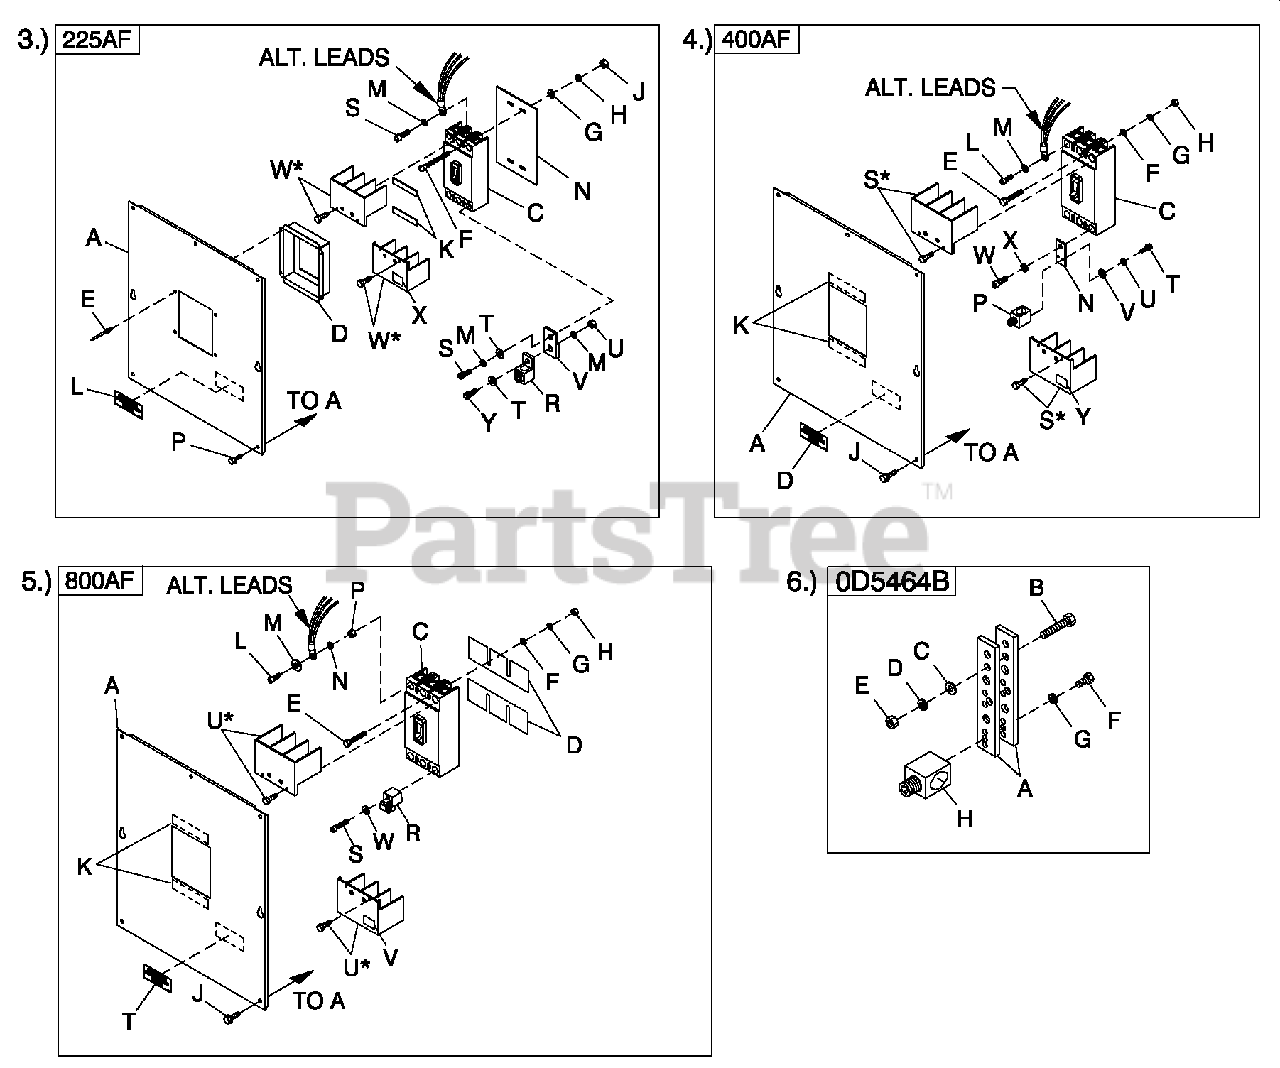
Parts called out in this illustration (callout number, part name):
A	COVER C B C 5 225AF
C	CIRCUIT BREAKERS 200A FRAME
D	COVER CB DISH 225AF
E	RIVET POP .125 X .275 S S
F	SCREW RHM #8-32X3-1/4
G	W ASHER FLAT #8 ZINC
H	WASHER LOCK #8-M4
J	NUT HEX #8-32 STEEL
K	TAPE ELEC 1/2 FOAM
L	DECAL CUSTOMER CONNECT INSIDE
M	W ASHER LOCK M8-5/16
N	INSULATOR CB225AF
P	SCREW THF M6-1 X 16 N WA Z/JS
R	LUG SLD LSS 300 MCM-6 AL/CU
S	SCREW SHC M8-1.25X20G8
T	W ASHER FLAT 5/16-M8 ZINC
U	NUT HEX M8-1.25 G8 CLEAR ZINC
V	BUS BAR 200A LUG ADAPTOR
W	TERMINAL COVER CB
X	DECAL TERMINAL SHOCK HZD BI
Y	SCREW SHC M8-1.25 X 25 G12.9
A	COVER C B C 5 400AF
C	CIRCUIT BREAKERS 400A FRAME
D	DECAL CUSTOMER CONNECT INSIDE
E	SCREW RHM 10-32X4
F	WASHER FLAT #10 ZINC
G	W ASHER LOCK #10
H	NUT HEX #10-32 STEEL
J	SCREW THF M6-1 X 16 N WA Z/JS
L	SCREW SHC M10-1.5X25G12.9
M	WASHER LOCK M10
N	BUS BAR CB ADAPTER 225-400 A
P	LUG SLD LSS 600/250-1/0 X 1/4-28
R	WASHER FLAT 3/8-M10 ZINC
S	TERM COVER CB
T	SCREW HHC 1/4-28 X 1/2 G5
U	WASHER LOCK M6-1/4
V	WASHER FLAT 1/4-M6 ZINC
W	SCREW SHC M10-1.5X25G12.9
X	WASHER LOCK M10
Y	DECAL TERMINAL SHOCK HZD BI
A	COVER C B C 5 800AF
C	CIRCUIT BREAKERS 800A FRAME
D	INSULATOR CB800AF
E	SCREW RHM 1/4-20X3-1/2
F	WASHER FLAT 1/4-M6 ZINC
G	W ASHER LOCK M6-1/4
H	NUT HEX 1/4-20 STEEL
J	SCREW THF M6-1X16 N WA Z/JS
L	SCREW SHC M10-1.50X 40 G12.9
M	WASHERFLAT 3/8-M10ZINC
N	WASHER LOCK 3/8
P	NUT HEX M10-1.5 G 8YEL CHR
R	LUG SLD LSS 3/0-400X3 MCM AL/CU
S	SCREW SHC M6-1.0X50G8.8
T	DECAL CUSTOMER CONNECT INSIDE
U	TERM COVERVITZROTECH 400AF CB
V	DECALTERMINALSHO CK HZD BI
W	W ASHER LOCK M6-1/4
A	BUS BAR NEUTRAL BLOCK 390
B	SCREW HHC M8-1.25 X 45 G8.8 FT
C	WASHERFLAT 5/16-M8ZINC
D	WASHER LOCK M8-5/16
E	NUT HEX M8-1.25G8YELCHR
F	SCREW HHC 1/4-28 X 3/4 G5
G	WASHER LOCK M6-1/4
H	LUG SLD LSS 600/250-1/0X1/4-28
